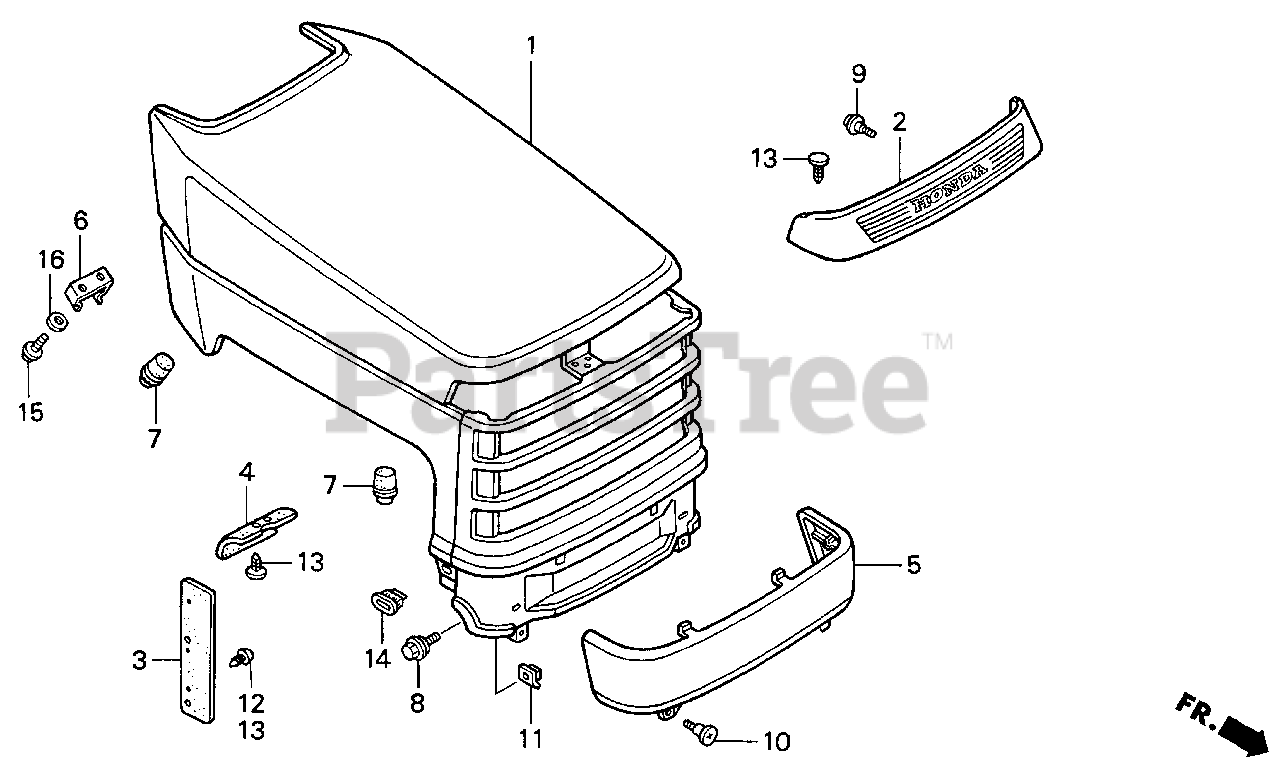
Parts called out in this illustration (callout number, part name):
1	HOOD *R165* (JOLLY RED)
3	SEAL, GRILLE SIDE
4	SEAL, GRILLE (UPPER)
5	BUMPER *R165* (JOLLY RED)
6	STRIKER, HOOD
7	STOPPER, TAILGATE (BLACK)
8	BOLT, HINGE (8MM)
10	SCREW, METER VISOR SETTING
11	WASHER, SETTING
12	CLIP, TRIM (5MM) *NH1L* (BLACK)
13	CLIP, COVER (5MM)
14	GROMMET ASSY., GARNISH
15	BOLT-WASHER (6X12)
16	WASHER, PLAIN (6MM)
